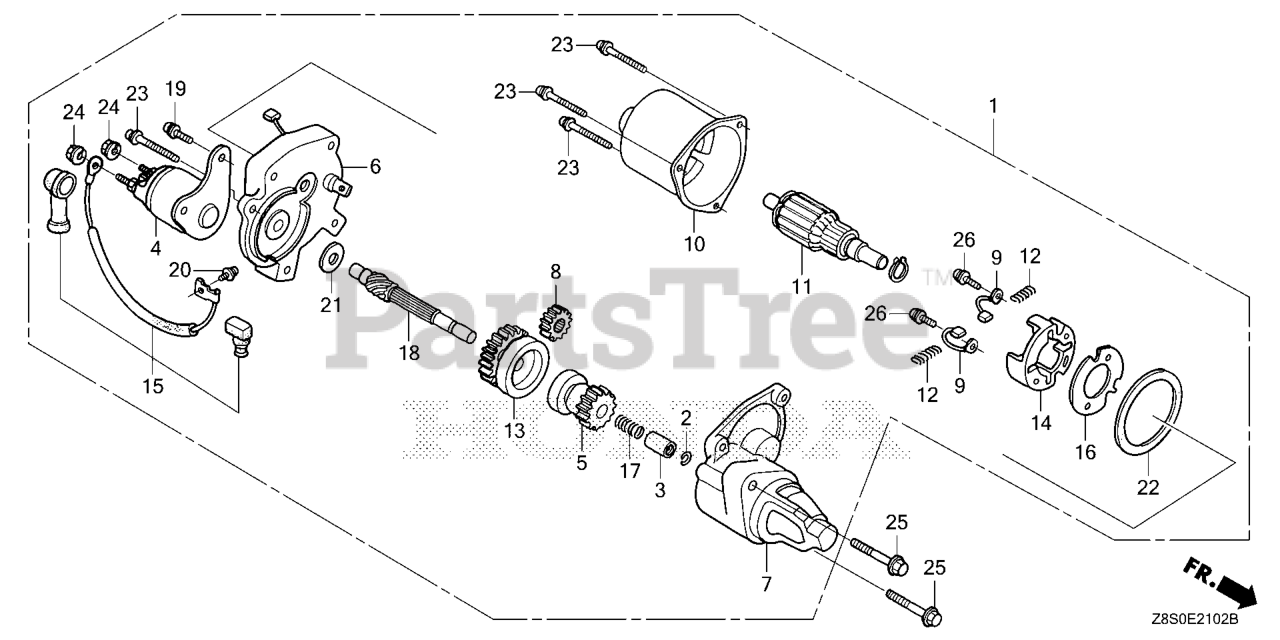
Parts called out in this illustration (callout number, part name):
1	STARTER MOTOR ASSY.
2	RING, SNAP
3	COLLAR, CLUTCH
4	CONTACTOR ASSY.
5	CLUTCH, OVERRUNNING
6	BRACKET, CENTER
7	BRACKET, FR.
8	GEAR, DRIVE PINION
9	BRUSH
10	YOKE
11	ARMATURE
12	SPRING, BRUSH RETURN
13	GEAR, REDUCTION
14	HOLDER, BRUSH
15	WIRE, WATER COVER
16	INSULATOR
19	BOLT-WASHER (5X14)
20	SCREW-WASHER (4X6)
21	WASHER, SK
22	GASKET
23	SCREW-WASHER (5X3)
24	NUT-WASHER (6MM)
25	BOLT, FLANGE (8X40) Use up to Engine SN 1003236.
26	SCREW-WASHER (4X14)
